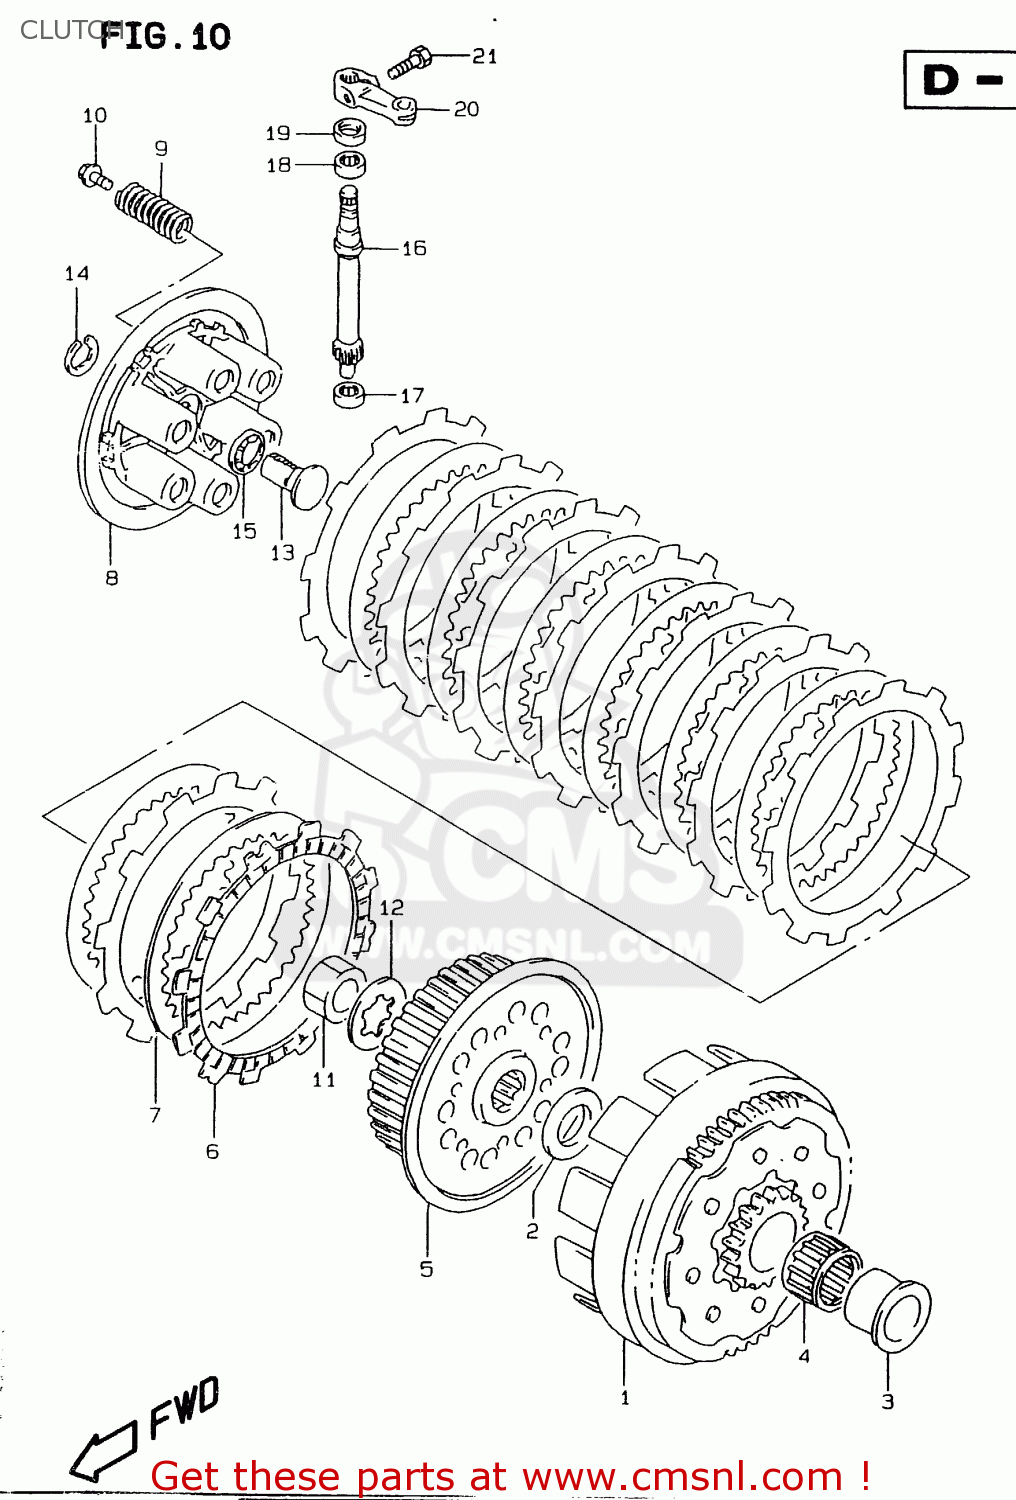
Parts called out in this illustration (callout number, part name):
1	GEAR ASSY,PRI DRIVEN
2	WASHER(22X38X2)
3	SPACER,PRIMARY DRIVEN GEAR
4	BEARING(29X34X21.8)
5	HUB,CLUTCH SLEEVE
6	PLATE,CLUTCH DRIVE (NAS)
7	PLATE,CLUTCH DRIVEN(T:1.6) (NAS)
8	DISC,CLUTCH PRESSURE
9	SPRING
10	BOLT(5X25)
11	NUT
12	WASHER,LOCK
13	RACK,CLUTCH RELEASE
14	CIRCLIP,10MM
15	BEARING(10X22X2.8)
16	PINION,CLUTCH RELEASE(NT:12)
17	BEARING(9X13X10)
18	BEARING(12X16X10)
19	SEAL,OIL(10X17X5)
20	ARM,CLUTCH RELEASE
21	BOLT
